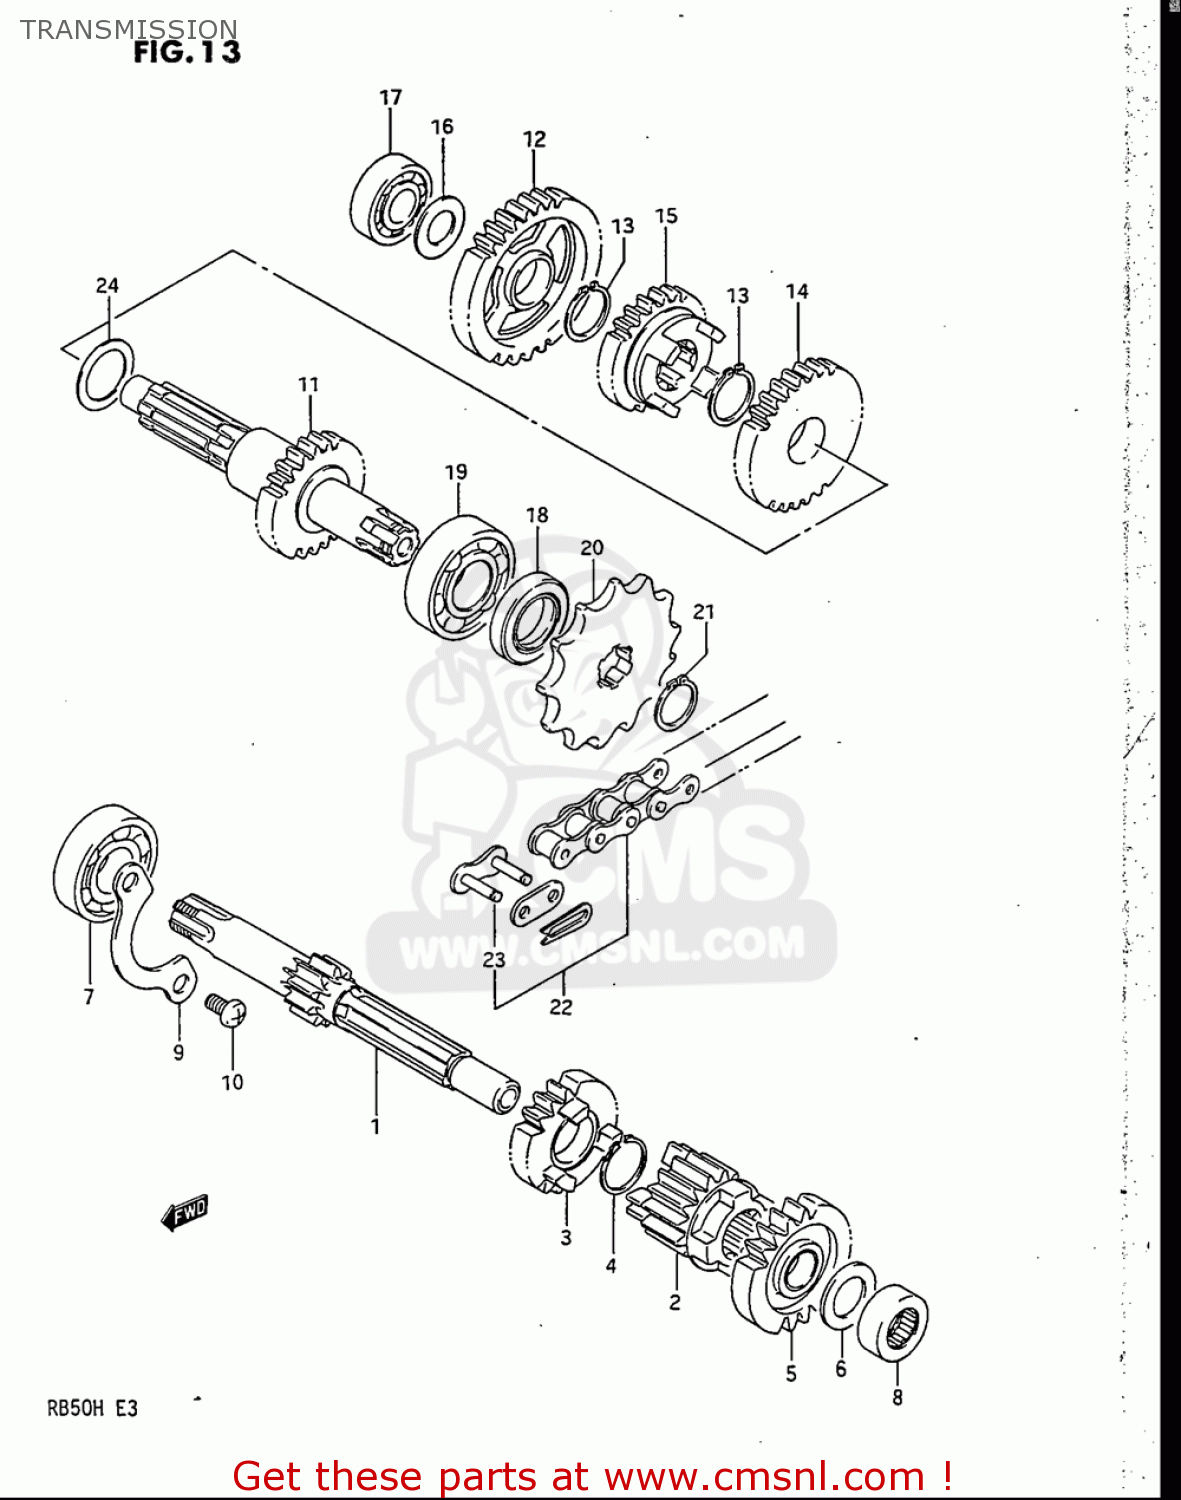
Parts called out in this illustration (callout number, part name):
6	WASHER
7	BEARING
8	BEARING(12X19X12)
10	SCREW
13	CIRCLIP,17MM
16	WASHER
17	BEARING
18	SEAL,OIL(17X30X7)
19	BEARING(17X40X12)
20	SPROCKET,ENGINE(NT:14)
21	CIRCLIP 16MM
22	CHAIN,DRIVE(420X130L)
23	JOINT
24	WASHER
